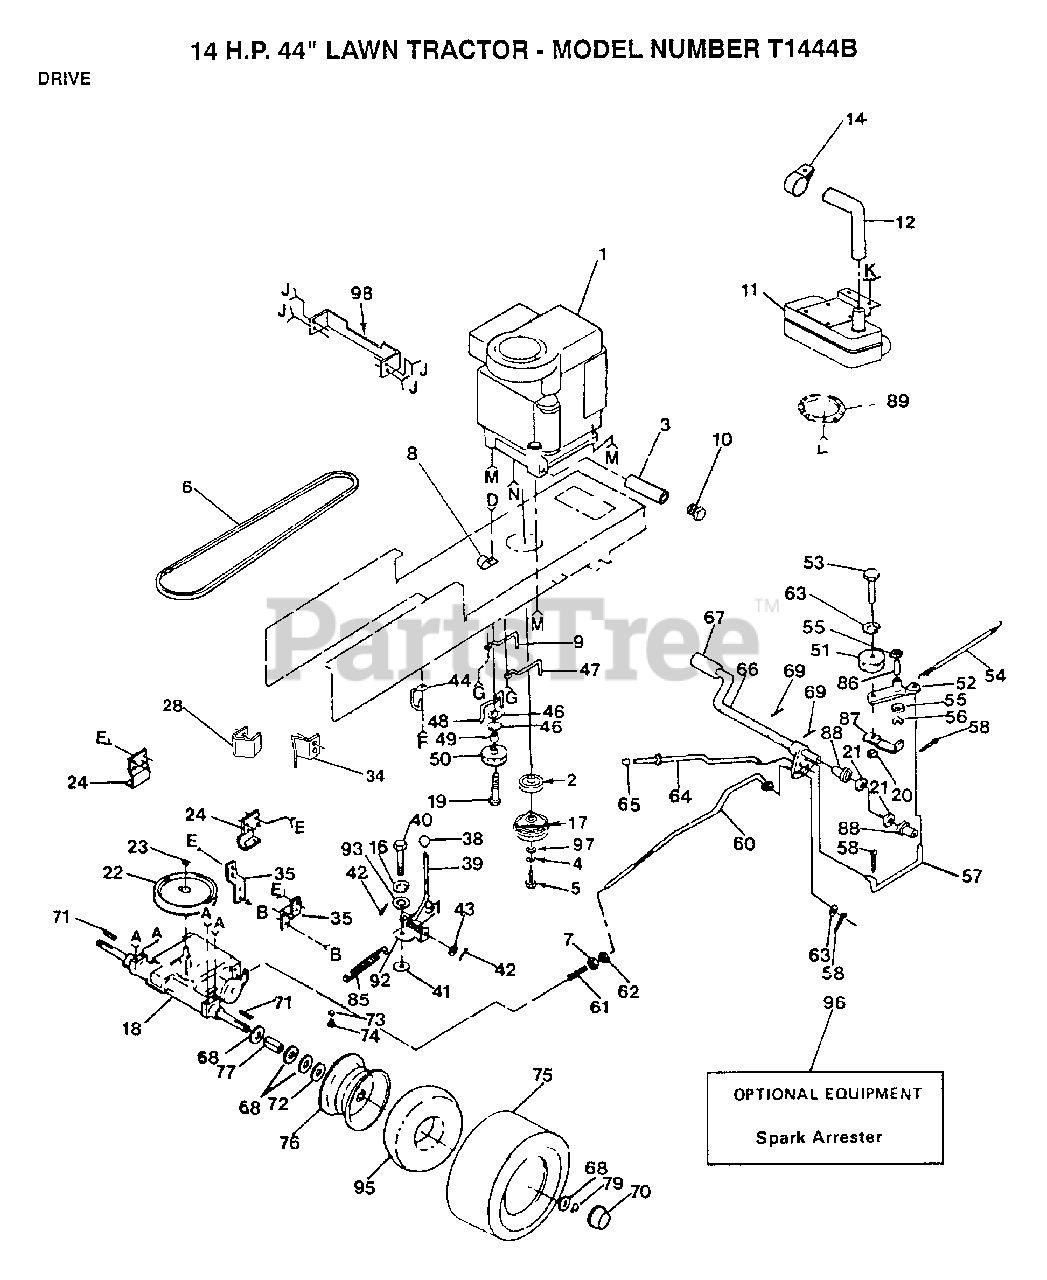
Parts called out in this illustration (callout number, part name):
4	LOCKWASHER
6	BELT-V.90.0.GD.DR
7	NUT
8	CLIP T
9	KEEPER BELT ENGLH
12	"TUBE,EXHAUST"
14	"CLAMP,MUFFLER"
16	LOCKWASHER
19	BOLT
21	WASHER LT
22	PULLEY TRANS
24	BRACKET LT
28	"KEEPER,BELT LH T"
34	"KEEPER,BELT RH T"
35	STRAP TORQUE
38	CONTROL KNOB LT
39	ROD SHIFTER
41	WASH-SHFT PLT LT
42	PIN COTTER 1/8
43	WASHER
46	WASHER
47	"KEEPER,BLT ENG LT"
48	BELT KEEPER LT
49	SPACER T
50	PULLEY.IDLER.FLAT
52	ARM IDLER
54	"SPRING, RETURN LT"
55	WASHER LT
56	KLIP RING
57	"LINK, CLUTCH T"
58	COTTER PIN
60	BRAKE ROD LT
61	SPRING ROD LT
62	NUT
63	WASHER
67	PEDAL COVER T
68	WASHER
70	HUB CAP
71	SQUARE KEY
72	WASHER
73	VALVE CAP
74	VALVE STEM LT
77	SPACER LT
79	E-RING LT
86	"LY, BEARING"
87	RETAIN BELT
88	NYLON BEARING
89	DEFLECTOR.222573
91	SPRING LT
92	PLATE SHIFT LT
93	WASHER LT
95	TUBE.18X9.5-8
96	SPARK ARREST KIT
97	WASHER
